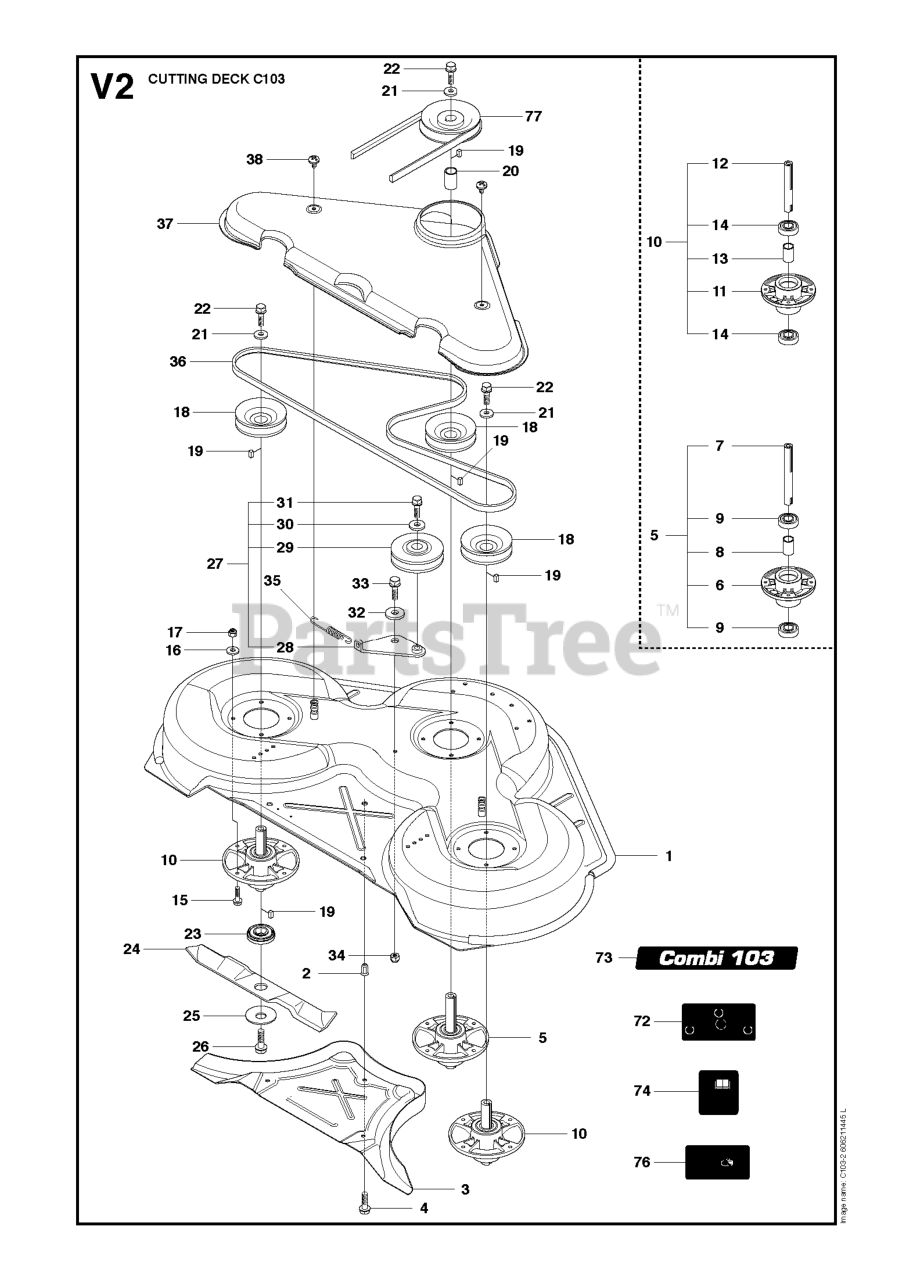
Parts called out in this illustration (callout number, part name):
6	BEARING HOUSING
8	SPACING SLEEVE
10	BLADE HOUSING ASSY
11	BEARING HOUSING
13	SPACING SLEEVE
16	WASHER BRB 8.4X17
17	LOCKNUT M8
20	SPACING SLEEVE
25	WASHER
27	BELT TENSIONER ASSY
28	BELT TENSIONING ARM
32	WASHER
34	LOCKNUT M8
